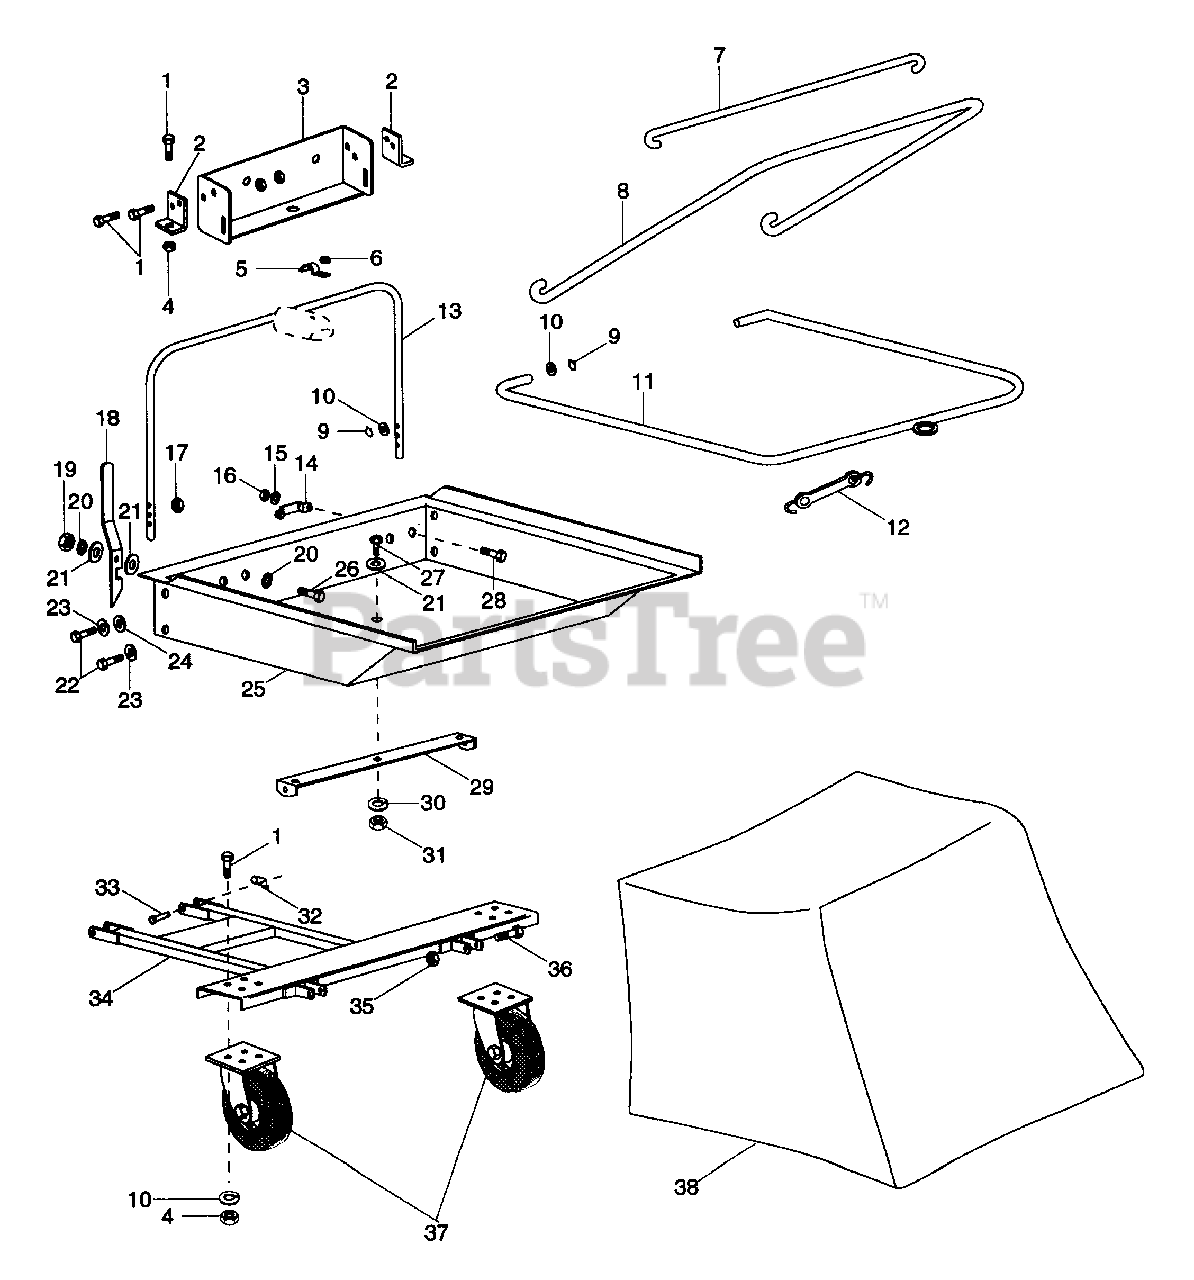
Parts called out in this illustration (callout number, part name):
1	BLT-HEX .38-16X1.00 PL
3	BRACKET, HITCH
4	NUT-HEX .375-16
5	SLEEVE CLAMP, 1" W/VINYL
6	NUT-LK-NYL .250-20 PL
7	ROD, STRAIGHT
8	ROD, SUPPORT
9	CIRCLE COTTER
10	WSHR-FL-STL .406X1.00X.062 PL
11	ROD, FRAME
12	STRAP, RUBBER 6 INCH
13	SUPPORT TUBE
14	HANDLE, LIFT
15	WSHR-LK .250X.047 LT PL
16	NUT-HEX .250-20 PL
17	NUT-LK .312-18 GR A PL
18	HANDLE, LATCH
19	NUT-LK .312-18 GR A PL
20	WASHER, SPRING 5/16
21	WSHR-FL-STL .328X.875X.062 PL
22	BLT-HEX .31-18X1.50 PL GR2
23	WSHR-FL-STL .323X.625X.062 PL
24	SPACER - PLASTIC,5/16
26	BLT-HEX .31-18X1.00 PL GR 2
27	SCR-MCH .31-18X.75 TSKBHD PL
28	SCR-MCH .25-20X.50 SLRH
29	U-BRACKET
30	WSHR-LK-INT .313X.030 PL
31	NUT-HEX .312-18
32	CLIP, SAFETY
33	PIN, CLEVIS, 1/2 X 1 1/4
35	NUT-LK-CROWN .50-13 GR C PL
36	BLT-HEX .50-13X1.25 PL GR2
37	WHEEL, SWIVEL 410/350-4
39	DECAL-ARIENS
